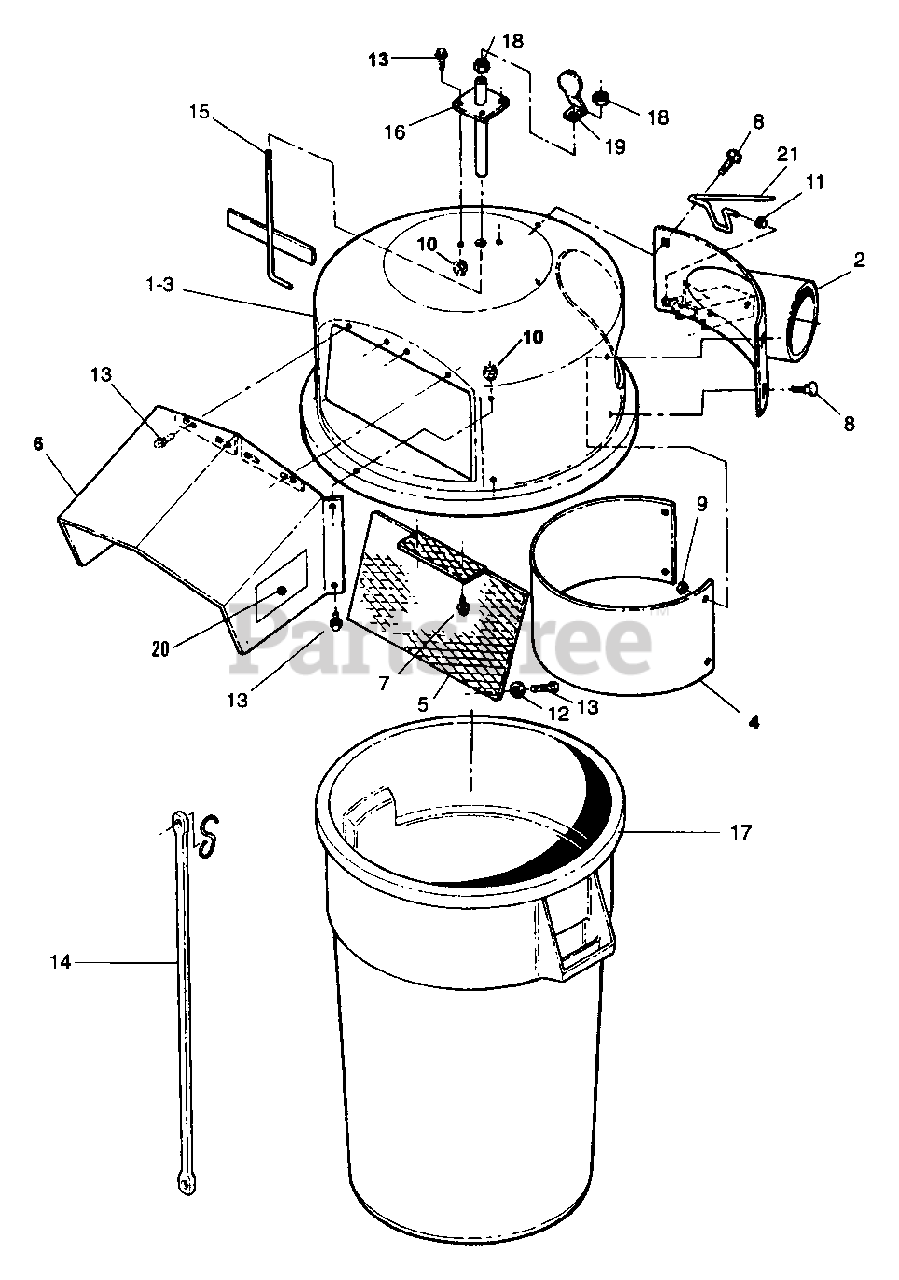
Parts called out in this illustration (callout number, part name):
1	ASSEMBLY, Catcher Top
2	WELDMENT, Container Inlet
3	TOP, Container
4	DEFLECTOR, Grass
5	SCREEN, Outlet
6	ASSEMBLY, Discharge Chute
7	SCREW, 1/4-15X3/4, Self-Tapping, BZ
8	BOLT, 5/16-18 x 1" Short Neck Carriage, Grade 5
9	NUT, 5/16-18 HEX NYLON LOCK
10	NUT, 1/4-20 HEX NYLON LOCK
11	NUT, 1/4" Push
12	WASHER, 1/4" Flat
13	SCREW, 1/4-20 x 3/4" Hex Head Cap, Grade 5
14	STRAP, Catcher Hold Down (With "S" Hooks)
15	WELDMENT, Rod - Paddle
16	WELDMENT, Tube - Plate
17	CONTAINER, Catcher
18	NUT, 1/4-20 Hex, Grade 5 or B
19	HOLDER, Decal
20	DECAL, Warning
21	ROD, Prop
